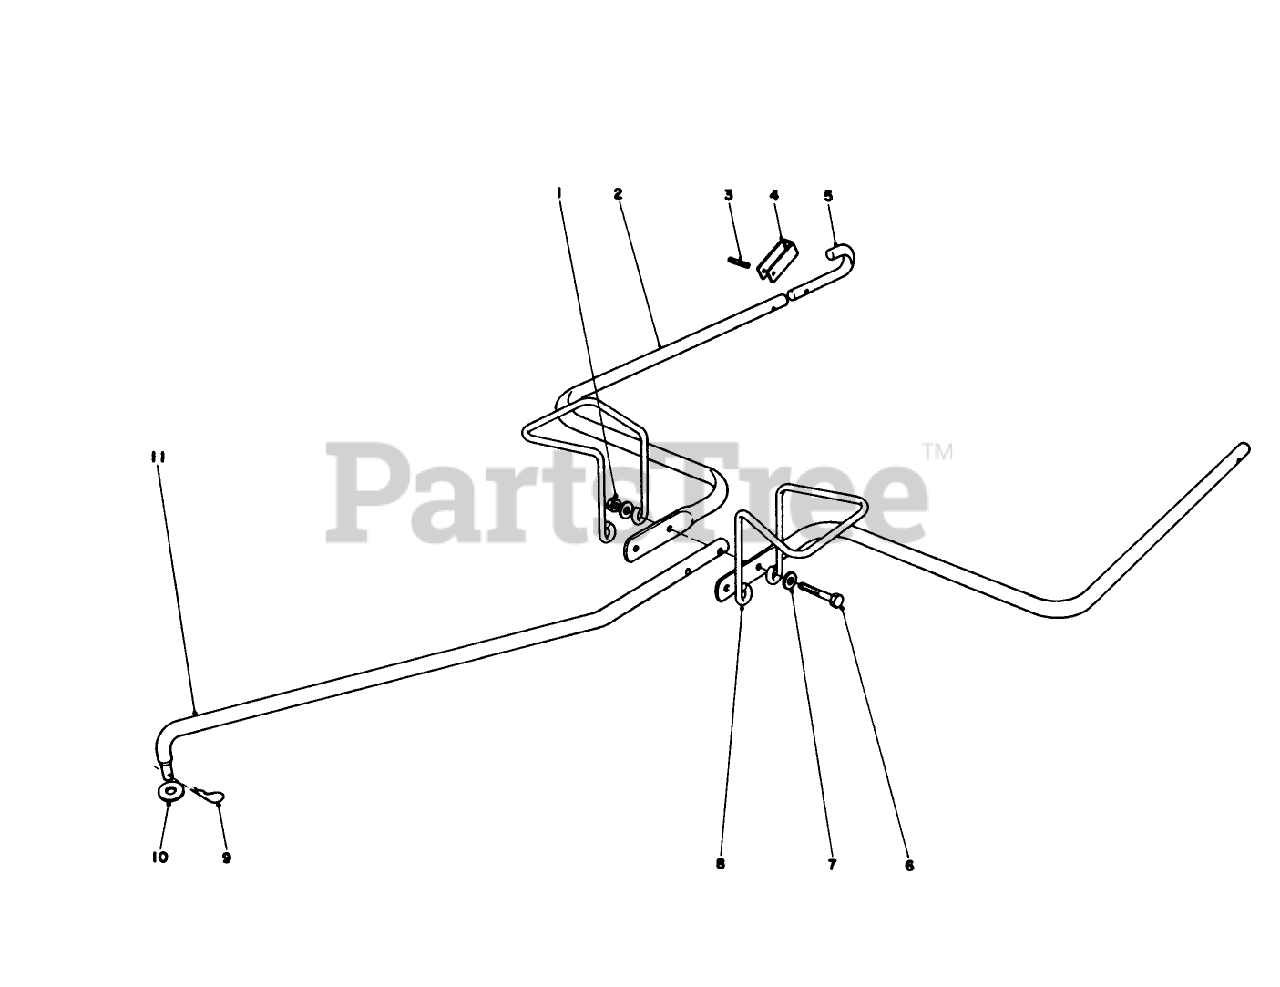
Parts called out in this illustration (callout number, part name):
2	HITCH ARM
3	PIN-ROLL, SLOT
4	HITCH LOCK
5	HOOK HITCH ARM
6	SCREW-HH
7	WASHER-FLAT
8	Support Bag
9	PIN-COTTER
10	PUSH NUT
11	POLE HITCH
